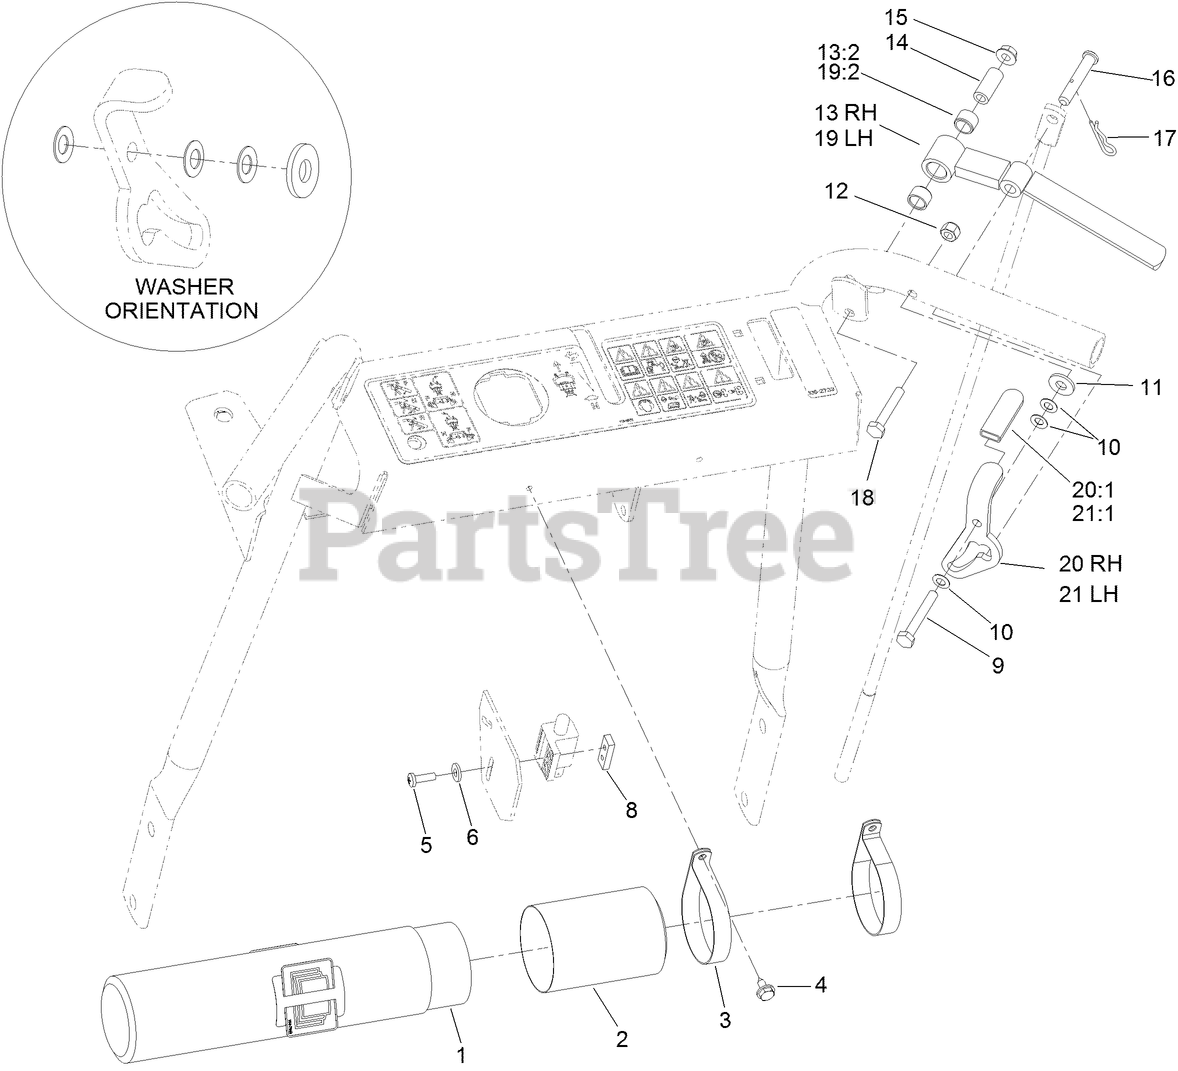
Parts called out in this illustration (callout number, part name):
1	TUBE-MANUAL
2	CAP-HOUSING
3	CLAMP-R
4	SCREW-HWHTF
5	SCREW-PPH
6	WASHER-FLAT
8	PLATE-TAPPED
9	SCREW-HH
10	WASHER-SPRING
11	WASHER-FLAT
12	NUT-LOCK, NI
13	RH Drive Lever ASM
13:2	BUSHING-SLEEVE
14	Bushing-Lever, Drive
15	NUT-HF
16	Pin-Clevis
17	PIN-COTTER
18	SCREW-HH
19	LH Drive Lever ASM
19:2	BUSHING-SLEEVE
20	RH LATCH and GRIP ASM
20:1	GRIP-LATCH
21	LH LATCH GRIP ASM
21:1	GRIP-LATCH
